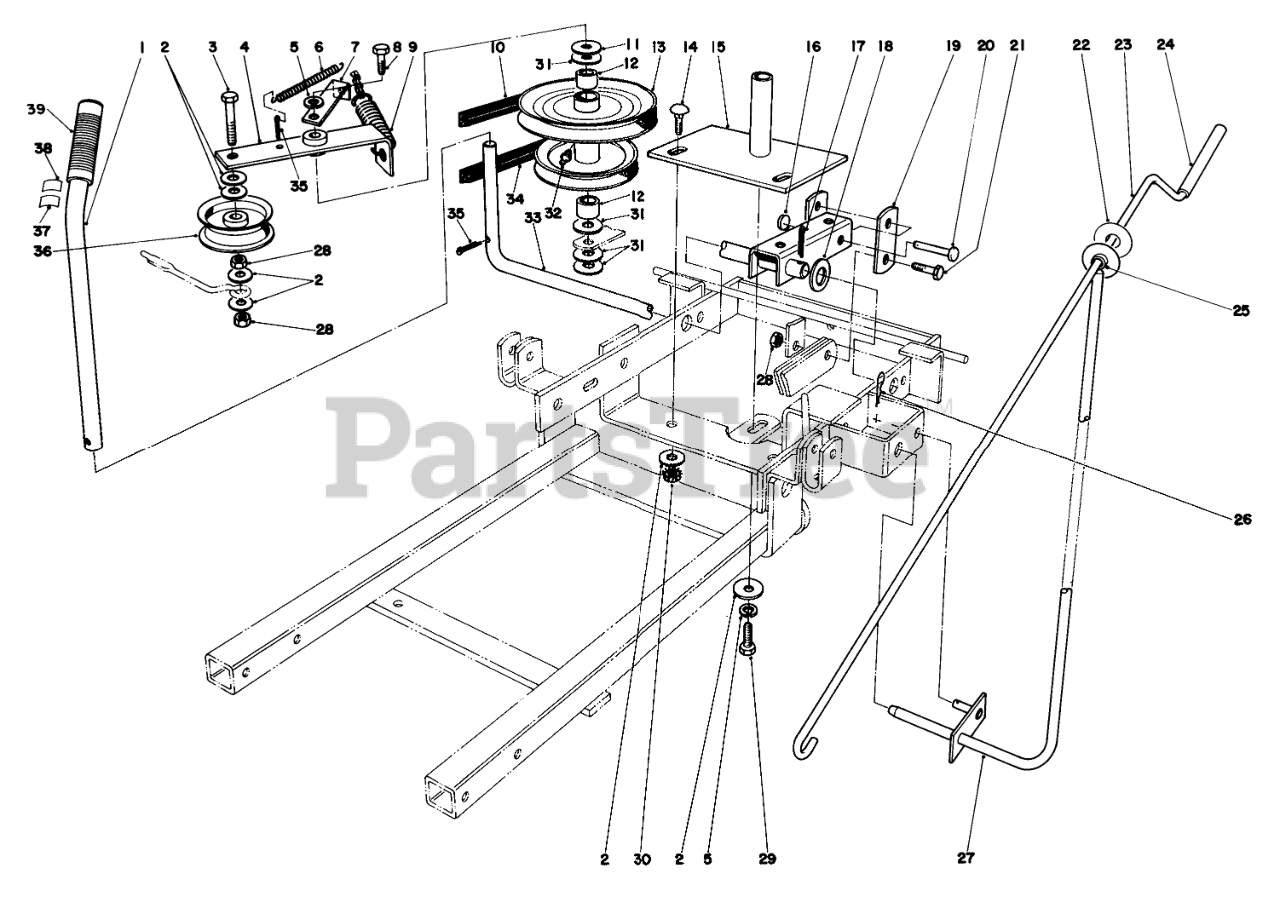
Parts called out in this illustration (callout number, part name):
1	Lift Handle
2	WASHER-FLAT
3	SCREW-HH
4	Idler Arm
5	WASHER-LOCK
6	Spring-Detent
7	Bracket-Spring Anchor
8	SCREW-HH
9	Spring
10	V-BELT
11	Washer
12	Roller Bearings
13	PULLEY HSG WA
14	BOLT-CARR
15	Mounting Bracket-Pulley
16	Spring Clip
17	PIN-COTTER
18	Spacer
19	Strap-Lift Link
20	Pin-Clevis, Handle
21	SCREW-HH
22	Decal-Spout Rotation
23	Rod-Deflector Control
24	Grip-Handle
25	Nylon Bushing
26	PIN-HAIR
27	Crank Rod Support (Incl. Ref. #22 & 25)
28	NUT-LOCK, CONE
29	SCREW-HH
30	NUT-KEPS
31	Washer
32	FITTING-GREASE
33	Lift Bar
34	V-Belt
35	PIN-COTTER
36	IDLER PULLEY ASM
37	Decal-Lift Control
38	Decal-Raise & Lower
39	GRIP-HANDLE
